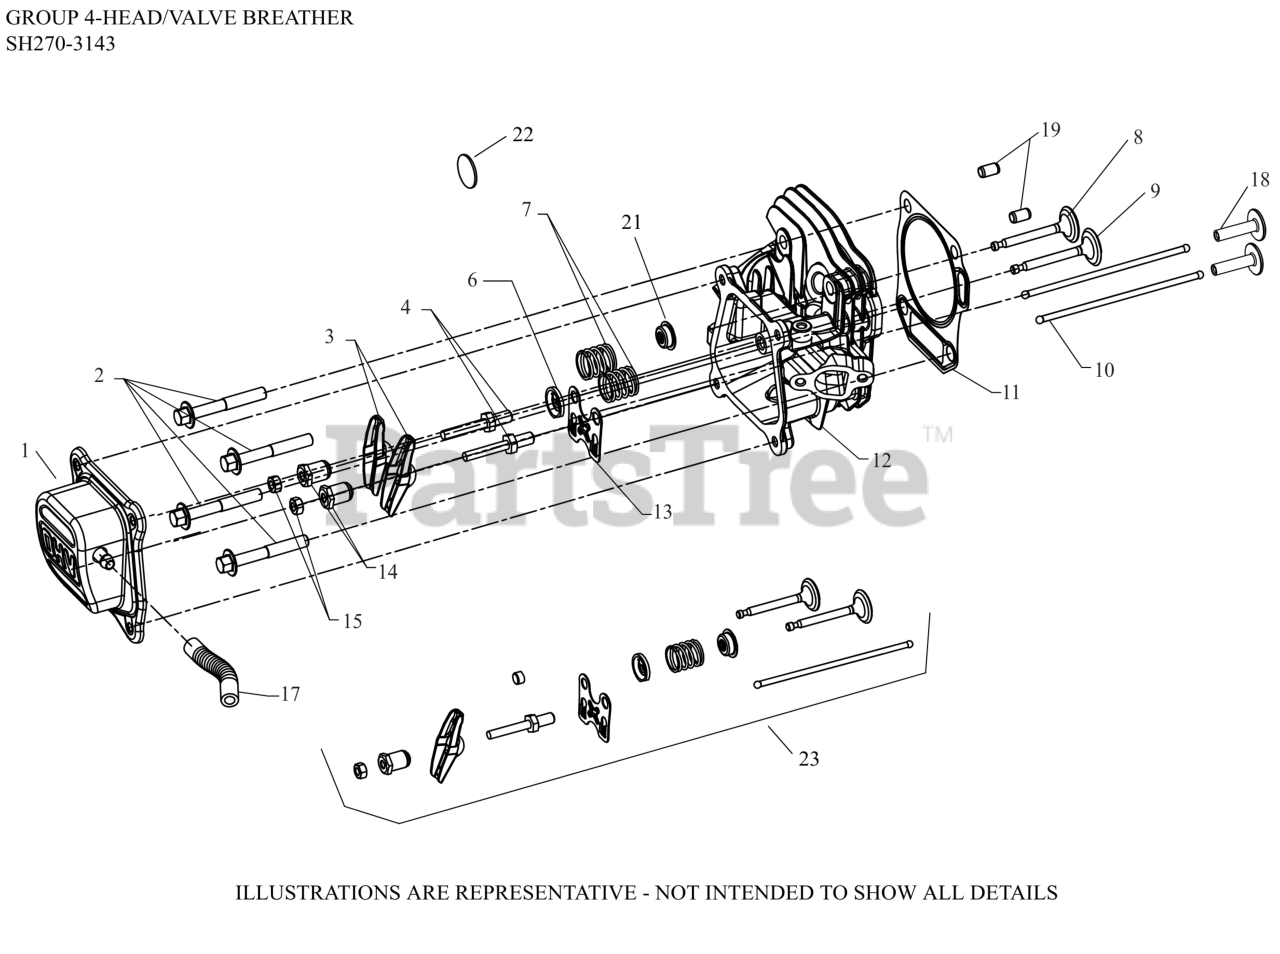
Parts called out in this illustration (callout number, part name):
1	COVER, VALVE ASSEMBLY
2	SCREW, HEX FLANGE CYL HEAD
3	ARM, ROCKER
4	STUD, ROCKER ARM-USE 14 072 22-S
6	RETAINER, VALVE SPRING
7	SPRING, VALVE
8	VALVE, EXHAUST
9	VALVE, INTAKE
10	ROD, PUSH
11	KIT, HEAD GASKET
12	HEAD ASSEMBLY, CYLINDER
13	PLATE, PUSHROD GUIDE
14	PIVOT, ROCKER ARM
15	NUT, HEX JAM
17	TUBE, BREATHER - (#1812313S)
19	PIN, DOWEL (8mm)
21	SEAL, VALVE STEM
22	REED, BREATHER
23	KIT, VALVE TRAIN
